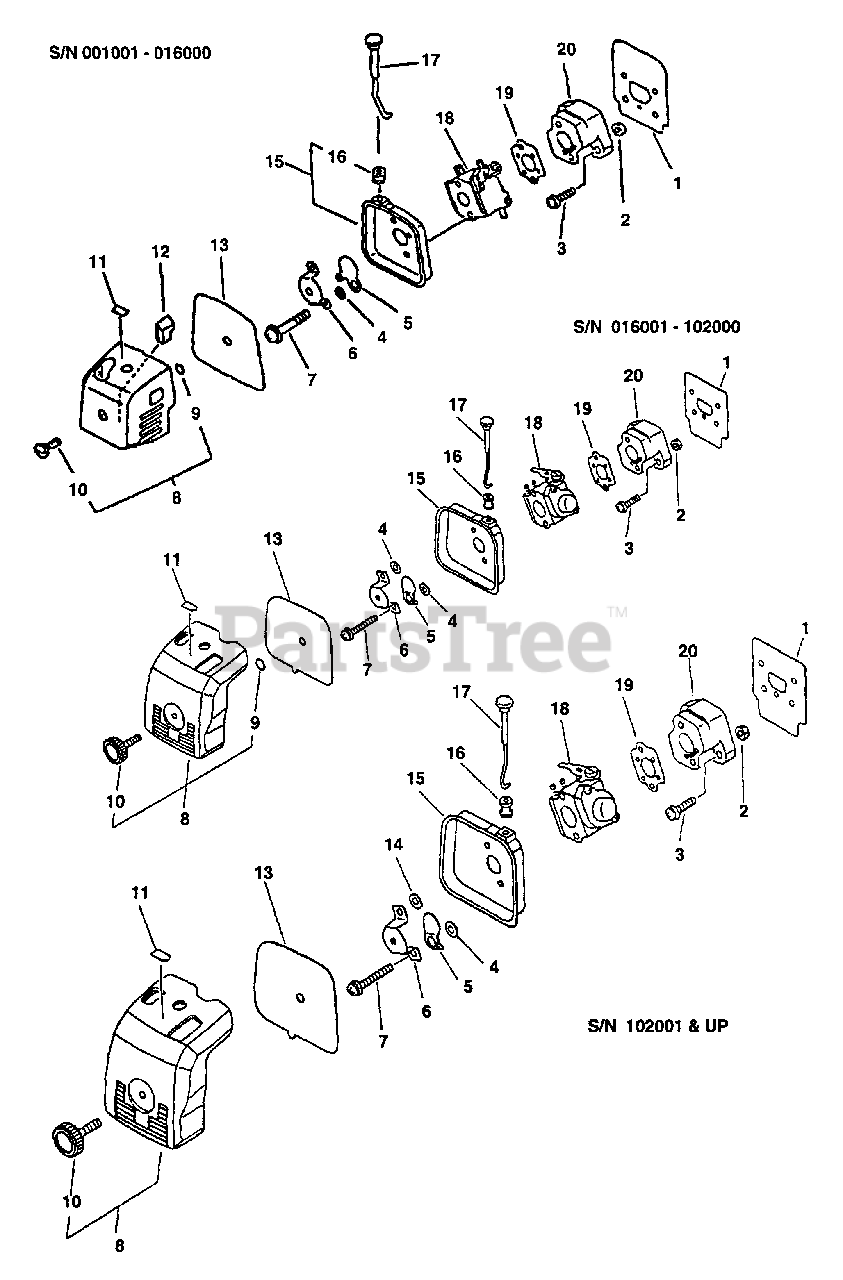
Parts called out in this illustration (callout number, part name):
1	HEAT SHIELD, INTAKE
2	NUT M5
3	SCREW 5×20
4	WASHER 5.2×8×0.8T
5	SHUTTER, CHOKE
6	CASE, AIR FILTER
6	PLATE, PREVENT
7	SCREW 5×57
8	AIR FILTER COVER ASSY
9	O-RING
9	O-RING 3
10	SCREW
10	THUMBSCREW
11	LABEL, CHOKE
13	FILTER, AIR
13	FILTER, HEAVY-DUTY AIR
14	WASHER, FLAT 5.5×10×0.8
15	CASE, AIR FILTER
16	GROMMET, CHOKE
17	ROD, CHOKE
18	CARBURETOR - C1U-K23A
18	CARBURETOR - WT-424A
19	GASKET, INTAKE
19	GASKET, CARBURETOR
20	INSULATOR, INTAKE
